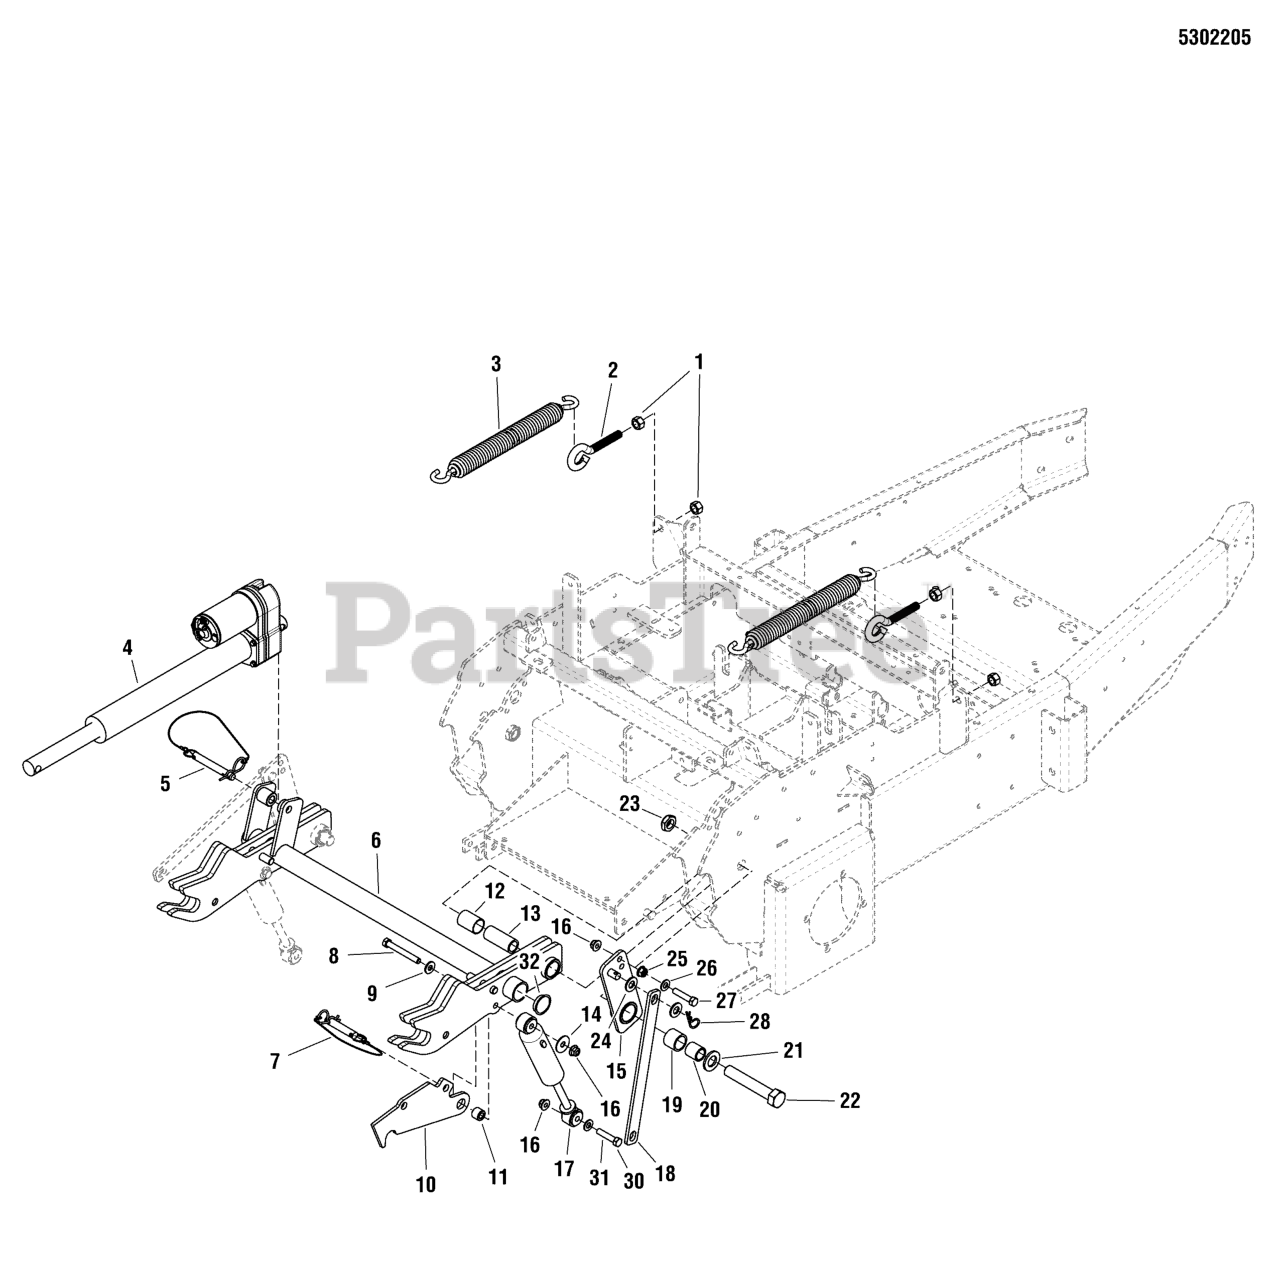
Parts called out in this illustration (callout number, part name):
1	NUT, 1/2-13 HEX
2	EYE BOLT, 1/2-13 X 5.5, 1" EYE, CZ
3	SPRING-EXT, 1.393ODX13.25LGX.218WR
4	ACTUATOR, 12" STROKE
5	HITCH PIN ASSY., 1/2 X 3.50
6	WELD, ATTACHMENT MOUNT - RED
7	HITCH PIN ASSEMBLY, 1/2" X 2.50"
8	BOLT, 3/8-16 X 3" GD5 CZ
9	WASHER, 5/16 USS
10	LATCH, FRONT FRAME - RED
11	SPACER, .39 X .75 X .580
12	PIVOT BEARING-1.00 X 1.125 ODX1.50
13	SPACER, .75 X 1.00 X 2.38
14	WASHER-3/8 FENDER
15	WELD, SPRING MOUNT PIVOT - LH - RED
16	NUT, 3/8-16 HEX NYLOCK FLANGE
17	SHOCK ABSORBER, OUT FRONT MOWER
18	BAR, SPRING ASSIST LINK - RED
19	BUSHING, BRASS, 1.00 X 1.25 X 1.00
20	SPACER, .76 X 1.00 X 1.06
21	WASHER, 3/4 SAE
22	BOLT, HEX HD, 3/4-16 X 4-1/2, GD5 YZ
23	NUT, 3/4-16, HEX JAM NYLON LOCK
24	WASHER, 1/2 SAE
25	NUT, 3/8-16 HEX SERRATED FLANGE
26	WASHER, 5/16 USS
27	BOLT, 3/8-16 X 1-3/4" GD5 CZ
28	PIN, HAIR, .0915 X 1-7/8
29	WELD, SPRING MOUNT PIVOT - RH - RED
30	BOLT, 3/8-16 X 2-1/4" GD5 CZ
31	WASHER, 3/8 SAE
32	PLUG, PANEL, 1.25 - BLACK
